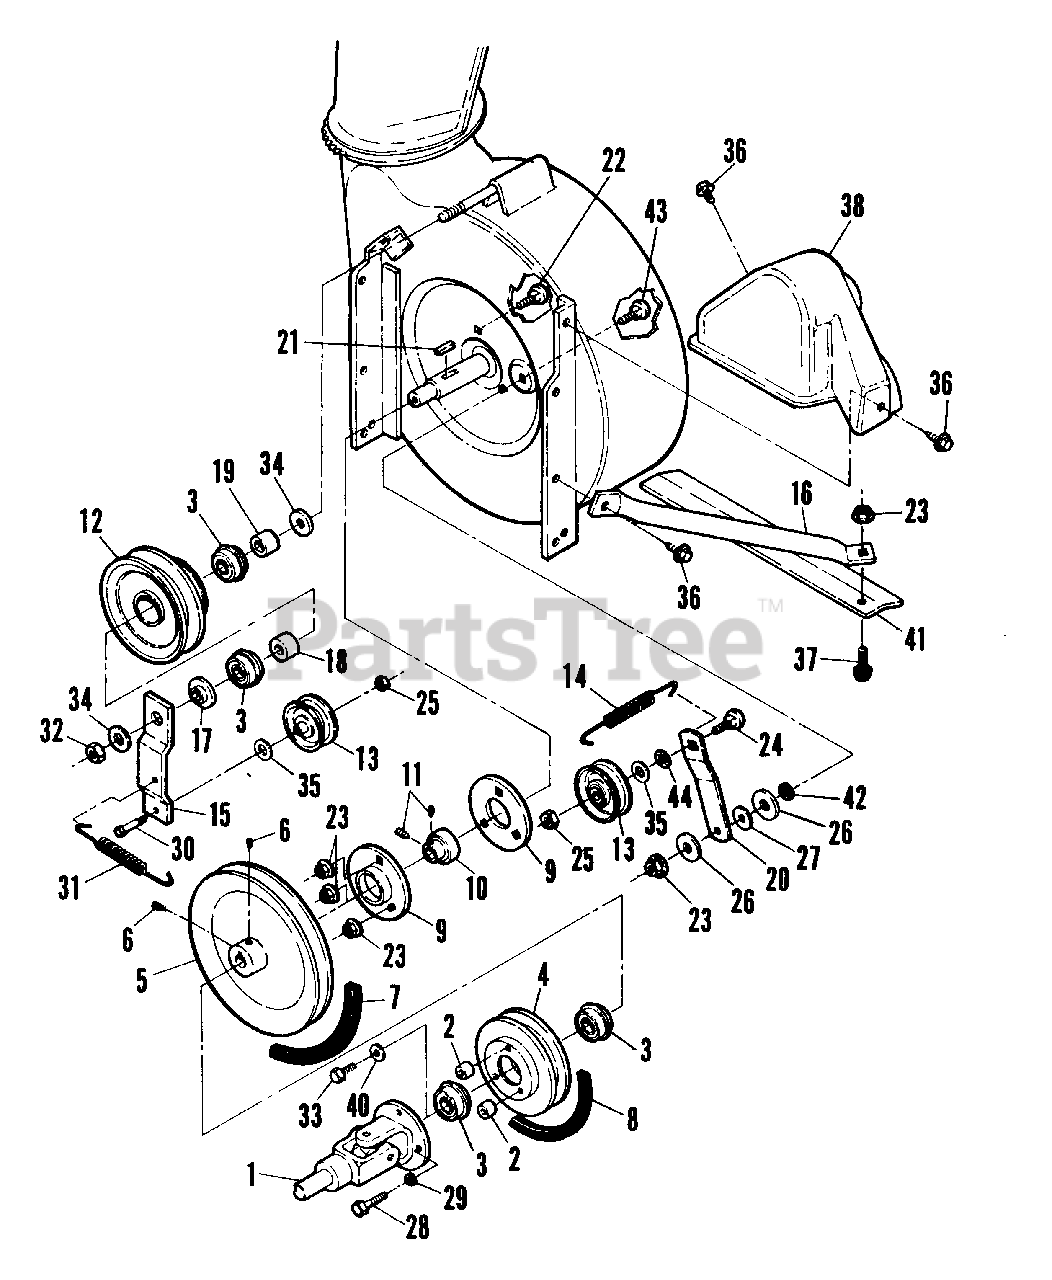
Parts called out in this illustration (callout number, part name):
1	SHAFT, Drive
2	SPACER, .328 x .63 x .50
3	BEARING
4	PULLEY, 5.25" O.D. (Iron)
5	PULLEY, 8.36" O.D.
6	SCREW, 5/16" Socket Head Set
7	V-BELT 35.24
8	V-BELT 34
9	HOUSING, Bearing
10	BEARING
11	SCREW, #10 - 32 Socket Head Set
12	SHEAVE, Reduction
13	IDLER, 2.47" O.D.
14	SPRING, Idler 5"
15	ARM, Idler
16	BRACE, R.H.
17	BUSHING, Step .64 x 1.5 x .265
18	SPACER, .64 x .88 x .765
19	SPACER, .64 x .88 x 1.283
20	ARM, Idler
21	KEY, 3/16 x 7/8" Woodruff
22	BOLT, 5/16 - 18 x 3/4" Short Neck Carriage
23	NUT, 5/16 - 18 Hex Flange Lock
24	BOLT, 3/8 - 16 x 1-1/2" Carriage
25	NUT, 3/8 - 16 Hex Lock
26	WASHER, 5/16" x 1-1/4" x 3/32" Flat
27	SPACER, .328 x .625 x .156
28	SCREW, 5/16 - 24 x 1 1/4" Hex Head Cap
29	WASHER, 5/16" Split Lock
30	SCREW, 3/8 - 16 x 1-1/2" Hex Head Cap
31	SPRING, 4"
32	NUT, 5/8 - 18 Hex Lock
33	SCREW, 5/16 - 18 x 5/8" Hex Thread Forming
34	WASHER, .656 x 1.312 x .094
35	WASHER, .406 x .812 x .080
36	BOLT, 5/16 - 18 x 3/4 Self-Tap
37	SCREW, 5/16 - 18 x 5/8" Hex Flange Lock
38	COVER, Belt
40	WASHER, .343 x .688 x .080
41	BAR, Stiffener
42	RETAINER, 5/16" Bolt
43	SCREW, 5/16 - 18 x 3/4" Short Neck Carriage
44	RETAINER, 3/8" Bolt
